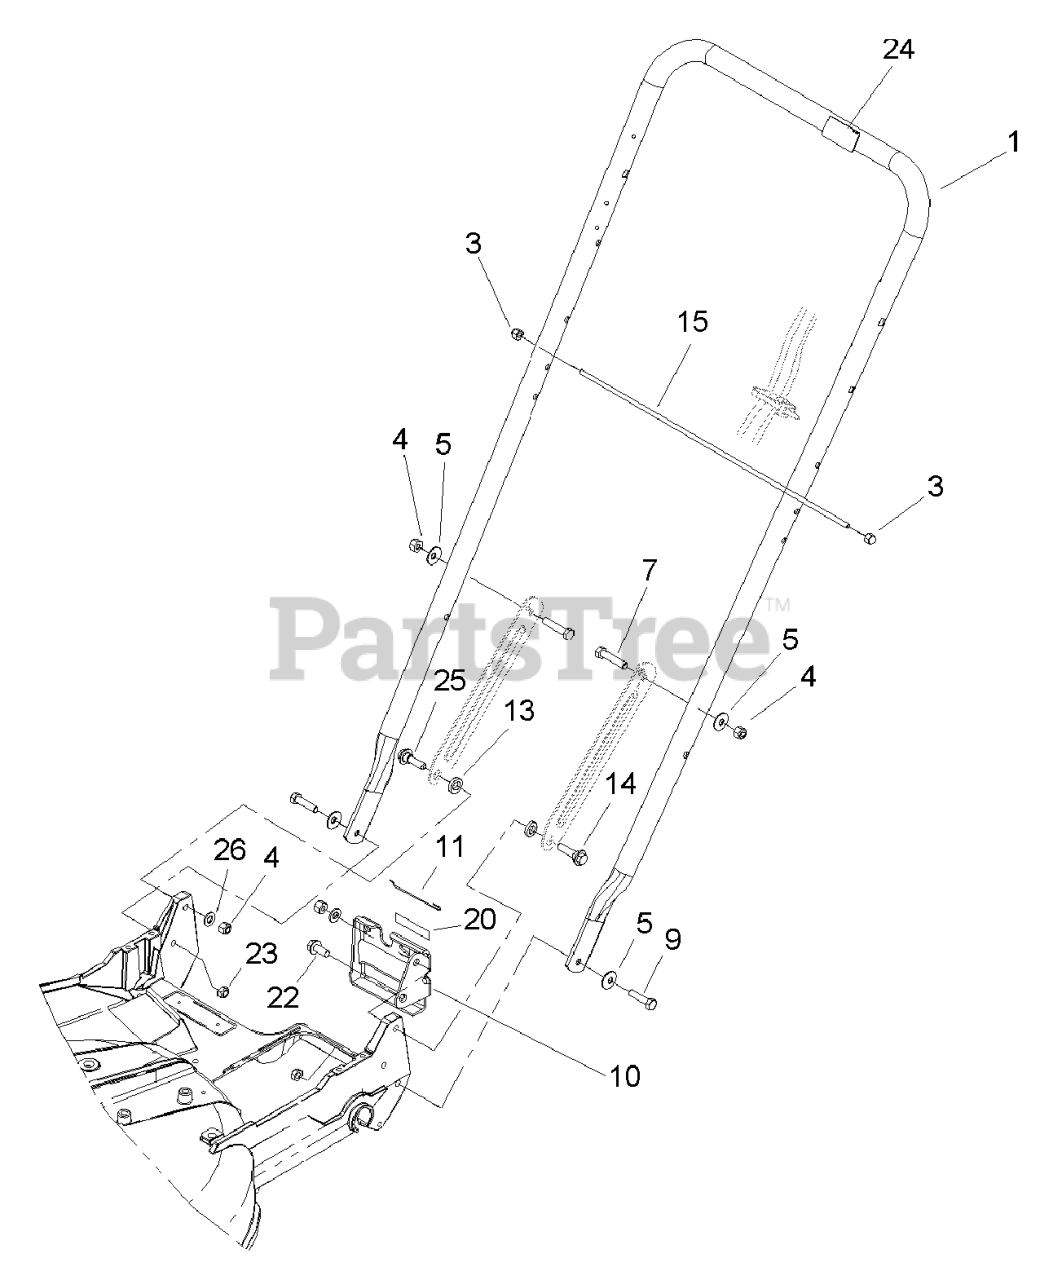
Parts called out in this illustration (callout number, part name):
3	NUT-CAP
4	NUT-LOCK, NI
5	WASHER-BELLEVILLE
7	SCREW-HH
9	SCREW-HH
10	BRACKET-ADJUSTMENT, TRACT
11	RETAINER-CABLE
13	SPACER
14	SCREW-SHOULDER
15	ROD-SUPPORT, BAG
20	DECAL-POSITION, GEAR
22	Screw-HWH 5/16-18 X 3/4 Tf
23	NUT-LOCK, NI
24	DECAL-PROTECTION, HEARING
25	SCREW-SHOULDER
26	WASHER-PLAIN
